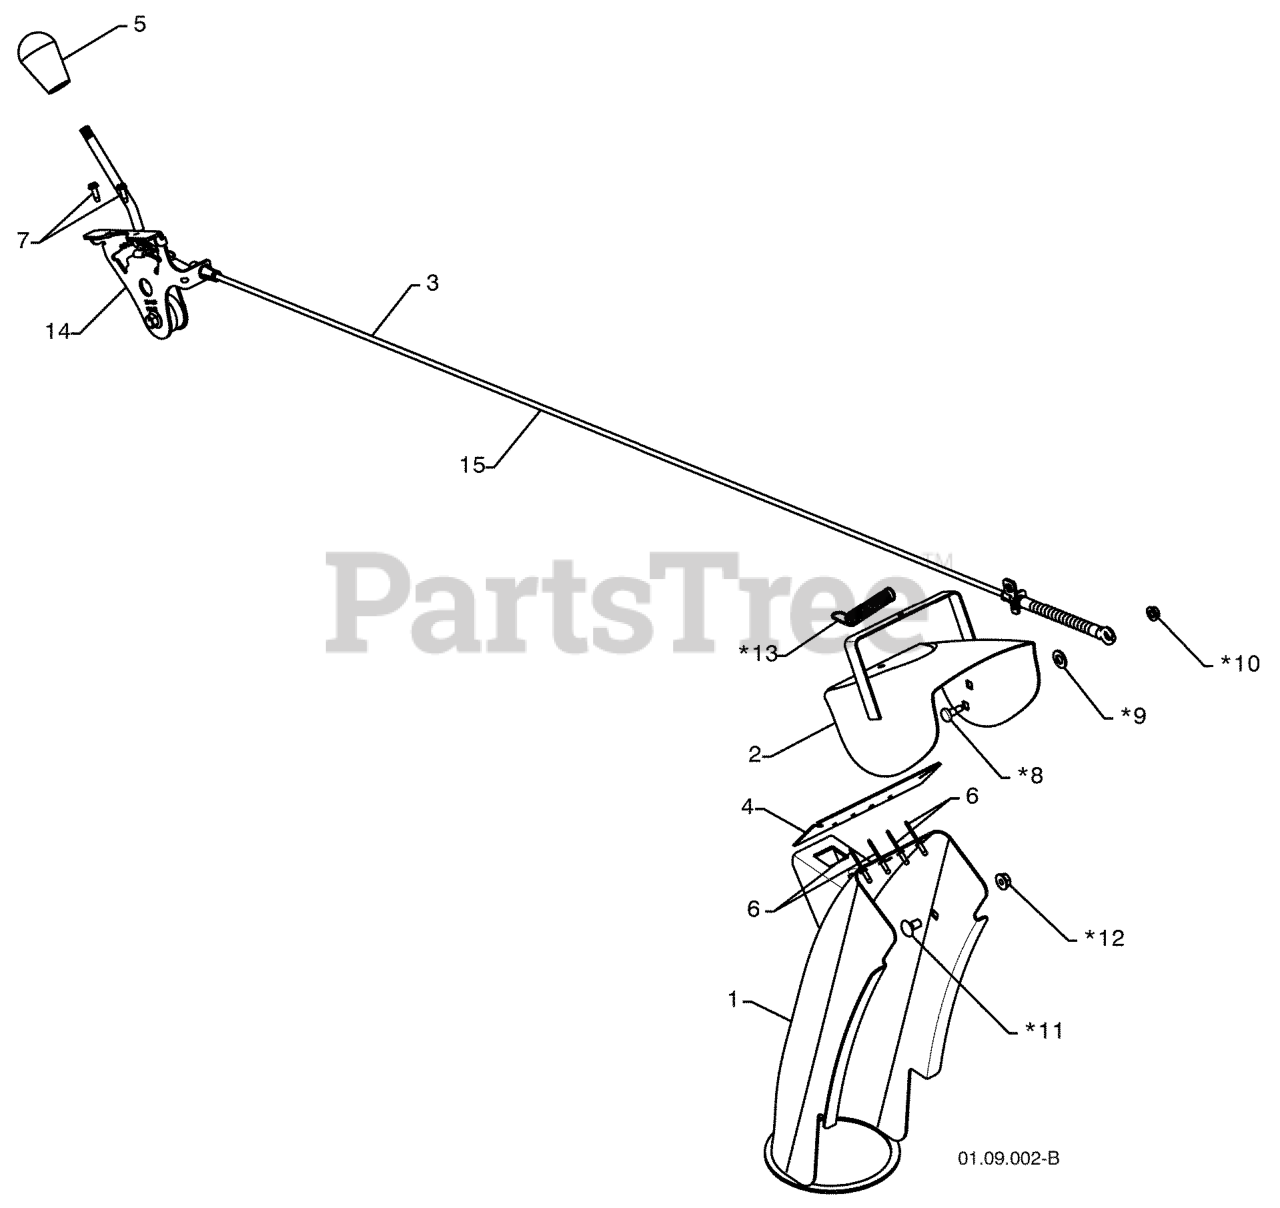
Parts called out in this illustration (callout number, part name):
1	CHUTE ASSEMBLY
2	DEFLECTOR.WELDMENT.PNT.ORANGE
3	RP.CONTROL.ASM.DEFLECTOR.SNOW
4	SEAL.DEFLECTOR
5	KNOB LEVER, BLACK
6	RIVET BLIND
7	SCREW #10-24 X 5/8
8	BOLT, SHOULDER
9	WASHER, NYLON FRICTION
10	NUT.HEX.FLANGE.1/4
11	BOLT
12	NUT.LOCK.5/16-18
13	SPRING.DEFLECTOR.REM.CHUTE
14	RP CNTRL.HEAD.ASSEM.DEFLECTOR
15	RB SERVICE.CHUTE.DEF.CBL.BLK
